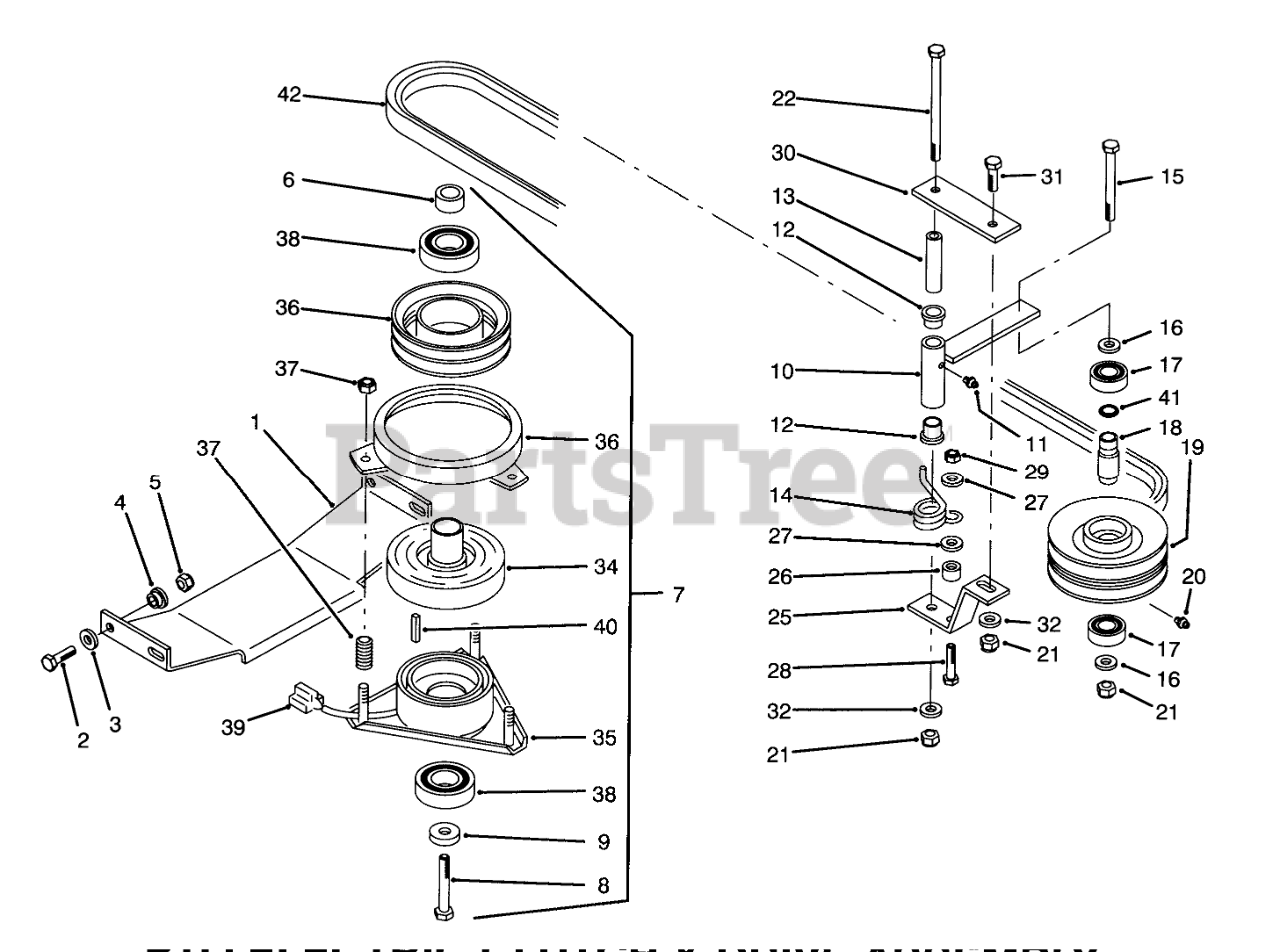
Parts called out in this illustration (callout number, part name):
1	BRACKET CLUTCH ST R
2	SCREW-HH
3	WASHER-PLAIN
4	BUSHING
5	NUT-LOCK, NI
6	SPACER
7	Electric Clutch Assembly (Incl. Ref. #6, 8, 9 & 34-40)
8	SCREW-HH
9	WASHER
10	Arm-Idler
11	Fitting-Grease
12	BUSHING
13	SPACER
14	SPRING-TORSION
15	SCREW-HH
16	Washer
17	BEARING-BALL
18	SPACER-PTO IDLER
19	PULLEY 2- GROOVE
20	FITTING-GREASE
21	NUT-LOCK, NI
22	SCREW-HH
25	Bracket-Idler
26	Spacer
27	WASHER-FLAT
28	SCREW-HH
29	NUT-LOCK, NI
30	Plate
31	SCREW-HH
32	WASHER-FLAT
34	ROTOR ASSEMBLY
35	Field Assembly (Incl. Ref. #38)
36	Armature & Pulley Assembly (Incl. Ref. #38)
37	ACCESS SPRING & NUT
38	BEARING-ELEC CLUTCH
39	CONNECTOR BODY B
41	O RING
42	V-BELT
